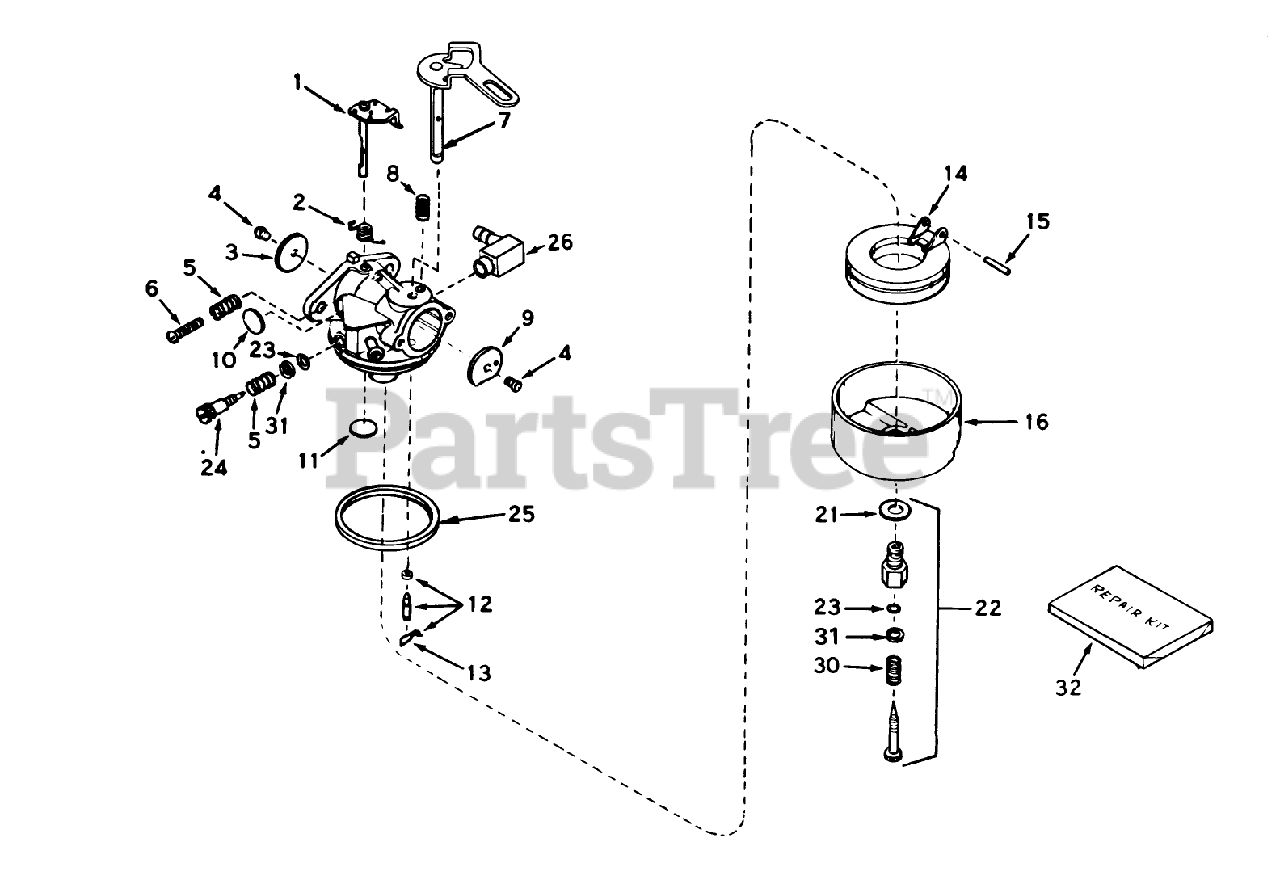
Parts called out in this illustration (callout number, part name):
1	Throttle Shaft and Lever ASM
2	Spring, Return
3	Shutter-Throttle
4	Screw-Shutter
5	Spring-Tension
6	Screw-Throttle Crack Screw / Idle Speed
7	Choke Shaft and Lever Asm
8	Spring-Positioning, Choke
9	Shutter-choke
10	Plug-Welch, Idle Mixture Well
11	Plug-Welch, Atmospheric Vent
12	Inlet Needle, Seat Clip Assy. (Incl. No. 13)
13	Clip-Spring
14	Float
15	Shaft-Float
16	Bowl-Float (no drain)
21	Washer-Bowl Nut
22	Adjustment Screw Assy., Main (Incl. Nos. 5A, 21 23)
23	ORing
24	Screw, Idle Adj.
25	O Ring-Bowl, Float
26	Fitting-Fuel
30	Spring
31	Washer
32	Repair Kit (Incl. items marked *)
